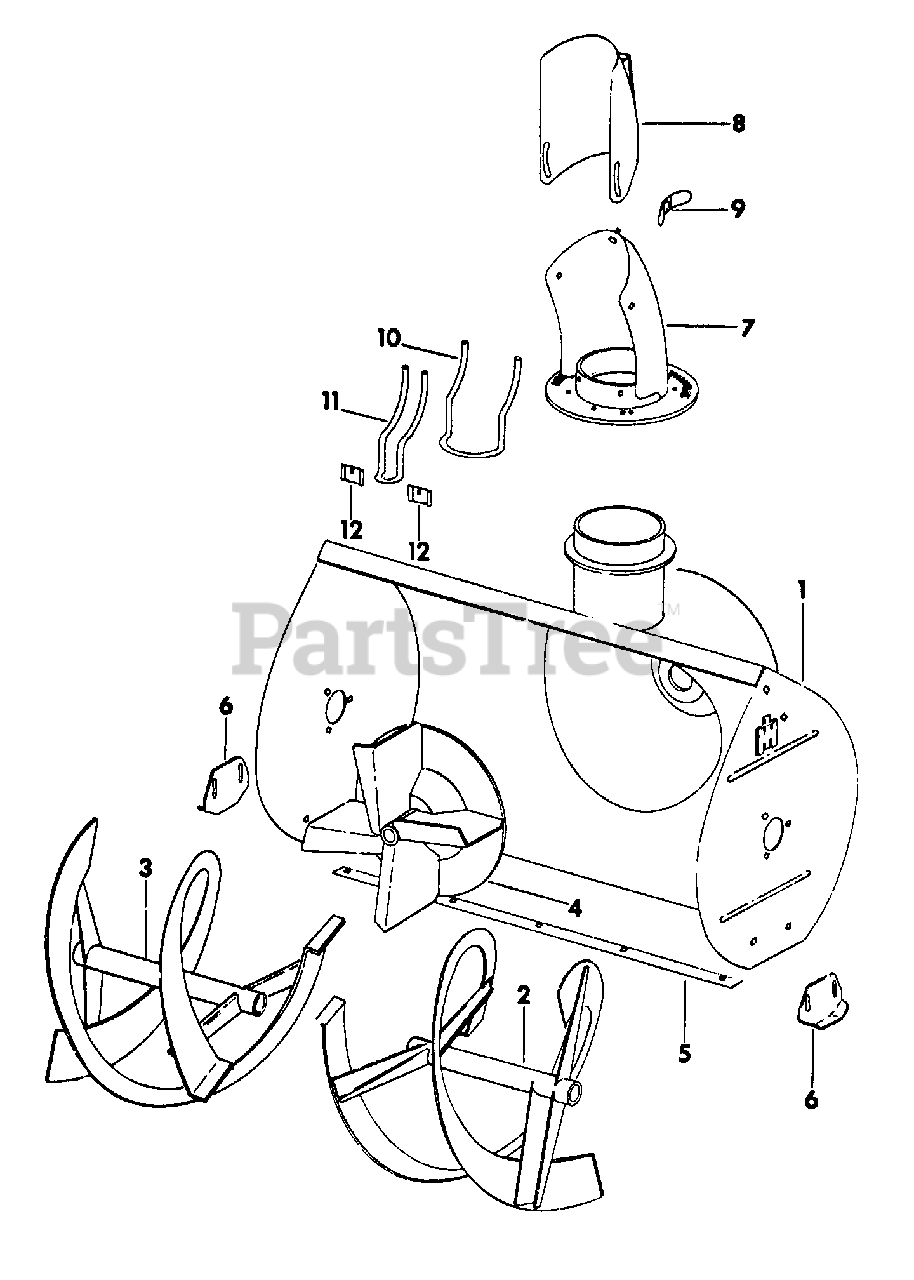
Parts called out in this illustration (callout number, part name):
1	HOUSING, WELDED
5	BLADE, SCRAPER
8	CAP W/CAUTION PRODUCT GRAPHIC, IH-73235-C2, DEFLECTOR
10	ROD, DEFLECTOR SIDE
12	CLAMP, DEFLECTOR
